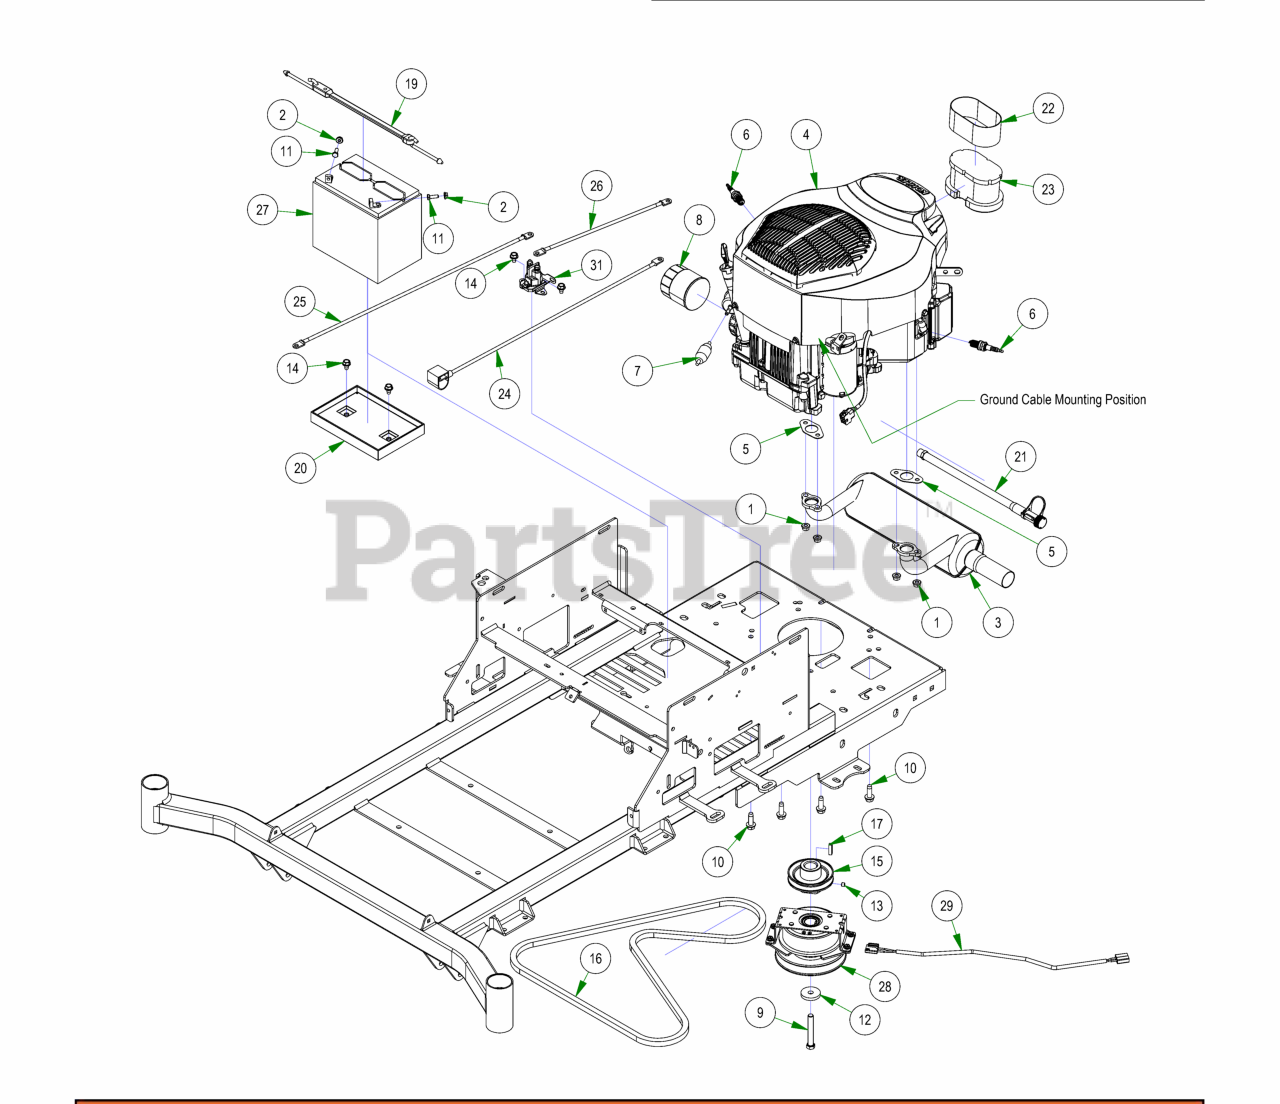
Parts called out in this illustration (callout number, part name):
1	M8 Nut Connects the 015-1012-00 and the 015-8240-00
2	1/4-20 HEX SERRATED FLANGE NUT HARD/ZINC
3	Kohler Muffler
4	KT745 Kohler Engine
5	Exhaust Gasket
6	Spark Plug
7	25/26 HP Kohler Fuel Filter
8	25 HP Kohler Oil Filter ZT?MZ
9	7/16-20x3” Hex Bolt GR 8 W/ Patch
10	3/8-16 X 1-1/8 HEX WASHER UNSLOT SERRATED (TRI-LOB) TRS ZINC YELLOW
11	1/4-20 X 3/4 HEX CAP SCREW (GR.5) ZINC
12	CLUTCH WASHER
13	5/16-24 X 1/4 SOCKET SET SCREW (CUP PT) PLAIN
14	5/16-18 X 1/2 HWH unslot (F) tcs zinc
15	3-3/4" Motor Pulley
17	1/4 X 1 SQ MACHINERY KEY 1018 STL PLN
18	2023 Battery Hold Down Assembly
19	2023 Rubber Battery Hold Down Strap
20	Battery Tray
21	Kohler Oil Drain
22	25/26 HP Koh Precleaner ZT/MZ
23	25/26 HP Koh Air Filter ZT/MZ
24	24 inch Black Cable – MZ/ZT
25	24" Red Battery Cable
26	12 in red battery cable
27	SP-35 Battery
29	Clutch Pigtail
30	2024 MZ-Avenger 54-60 Frame
